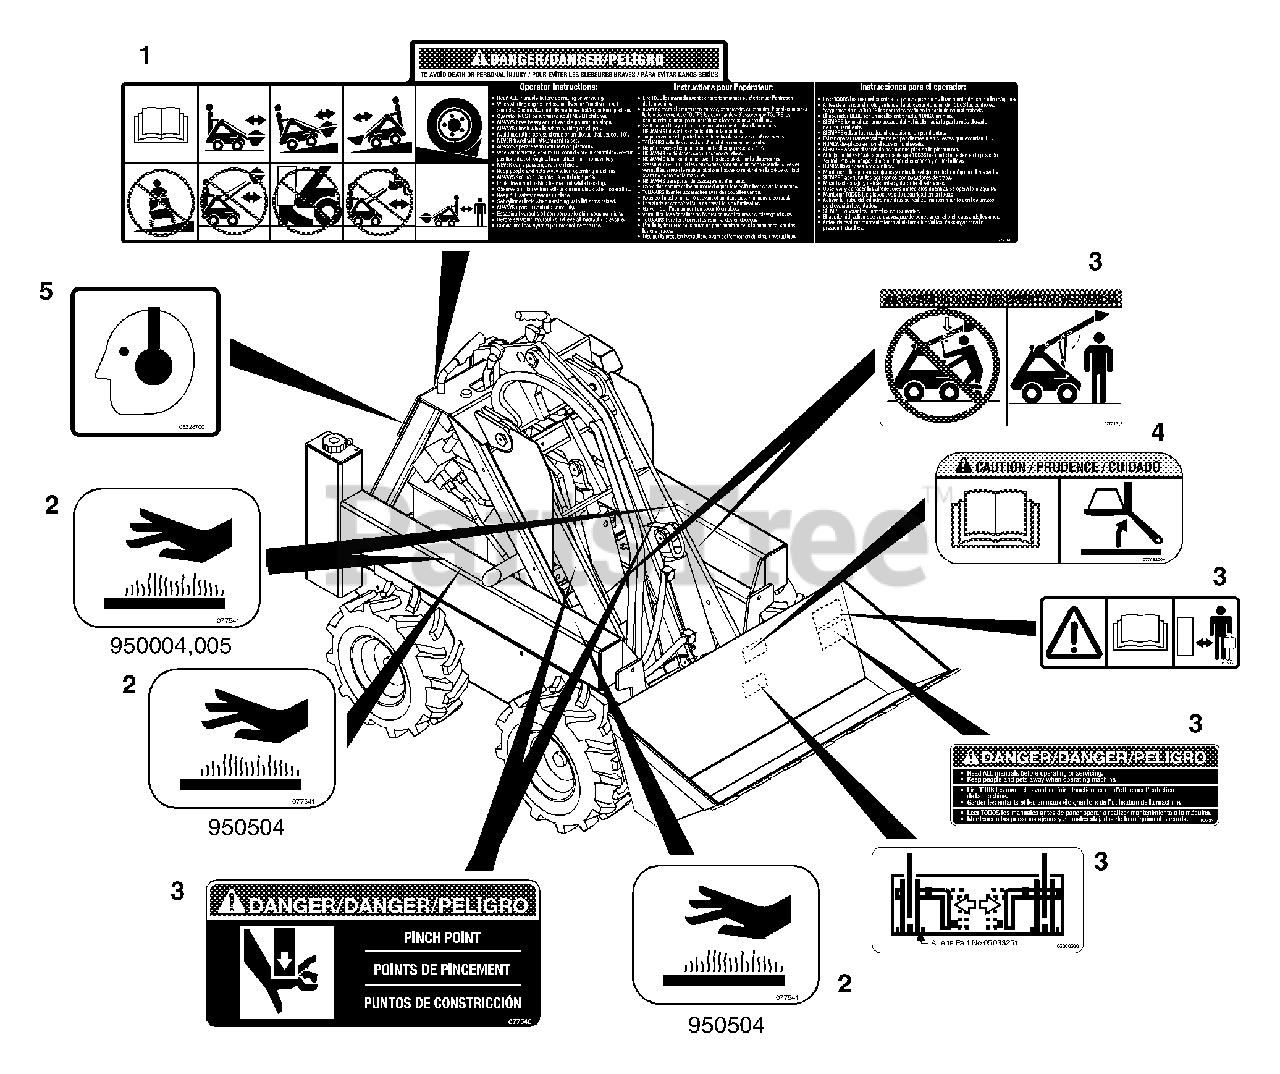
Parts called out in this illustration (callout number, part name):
1	Decal, Operator Safety Instruction
2	Decal, Hot Surface
3	Set, Decal
4	Decal, Weight Capacity
5	Decal, Ear Protection
